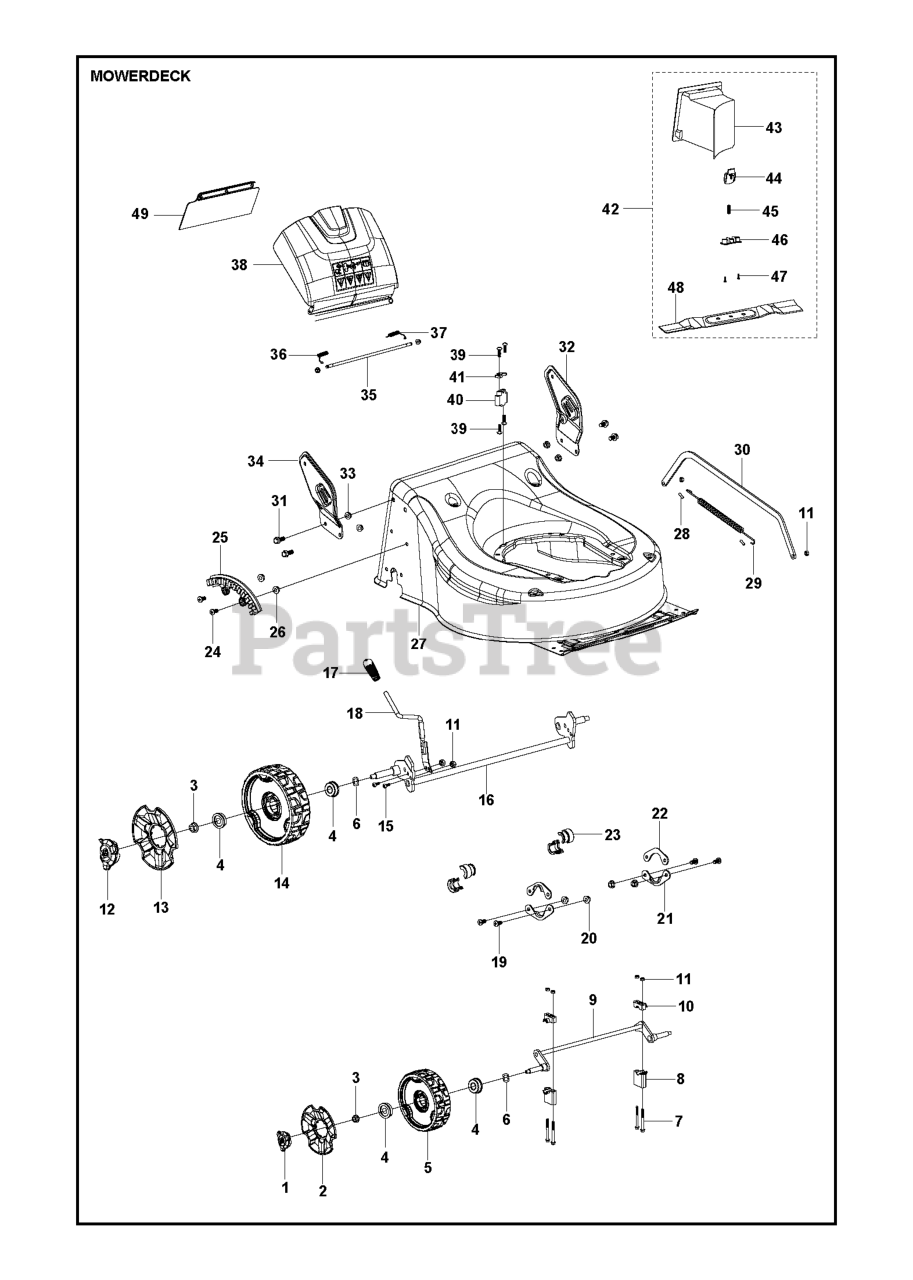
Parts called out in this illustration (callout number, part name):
1	WHEEL COVER 6" #25340700101
2	COVER 7 WHEEL COVER
3	LOCKING BOLT M8,GB6187.1 #2680
5	WHEEL ASSY 7 WHEEL
6	WASHER Ï?12 #26800706202
9	FRONT AXLE ASSY
11	LOCKING BOLT M6,GB889.1 #26800
12	WHEEL COVER 8" #25341000101
13	WHEEL COVER 8" #25341100101
14	WHEEL #25341300101
15	WASHER M6*14 #26800203001
16	REAR AXLE ASSY
17	KNOB HEIGHT ADJUSTMENT #25341
18	HANDLE ASSY
19	SCREW M6*16 #26800204601
20	LOCK NUT M6,GB/T6187.1-2000 #2
21	FIXING PLATE #26300124401
22	FIXING PLATE #26300314601
23	COVER AXLE #25235300101
25	SEGMENT #25214200102
28	TUBING #29000300101
29	SPRING #26801103903
30	CONNECTING ROD
31	BOLT M8*16 #26800606401
32	BRACKET LEFT
34	BRACKET RH
36	SPRING #26801125501
37	BRACKET #26801125401
38	COVER REAR FLAP
43	PLUG 25232600101
48	BLADE 26300349801
